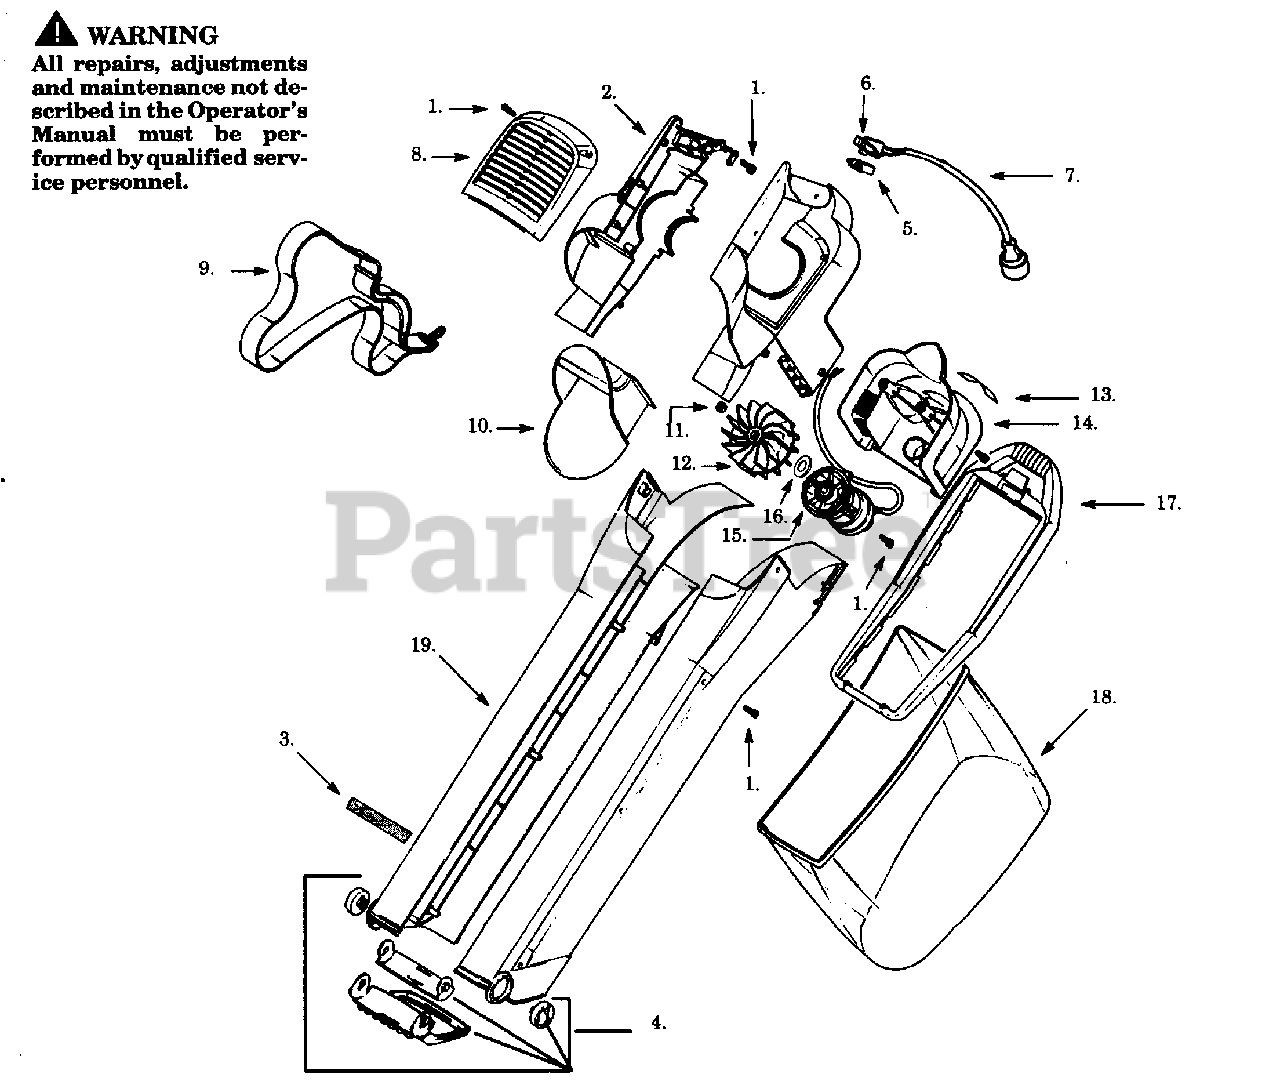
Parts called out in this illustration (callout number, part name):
2	Motor Hsg.
3	Decal (Not a serviceable part)
4	Kit-Wear Plate (Incl. Wear Plate, Valve & Control Valve Knobs)
5	Switch Actuator
7	Power Cable
12	Impeller
13	Warning Label
14	Motor Cover
17	Bag Frame
18	Debris Bag
